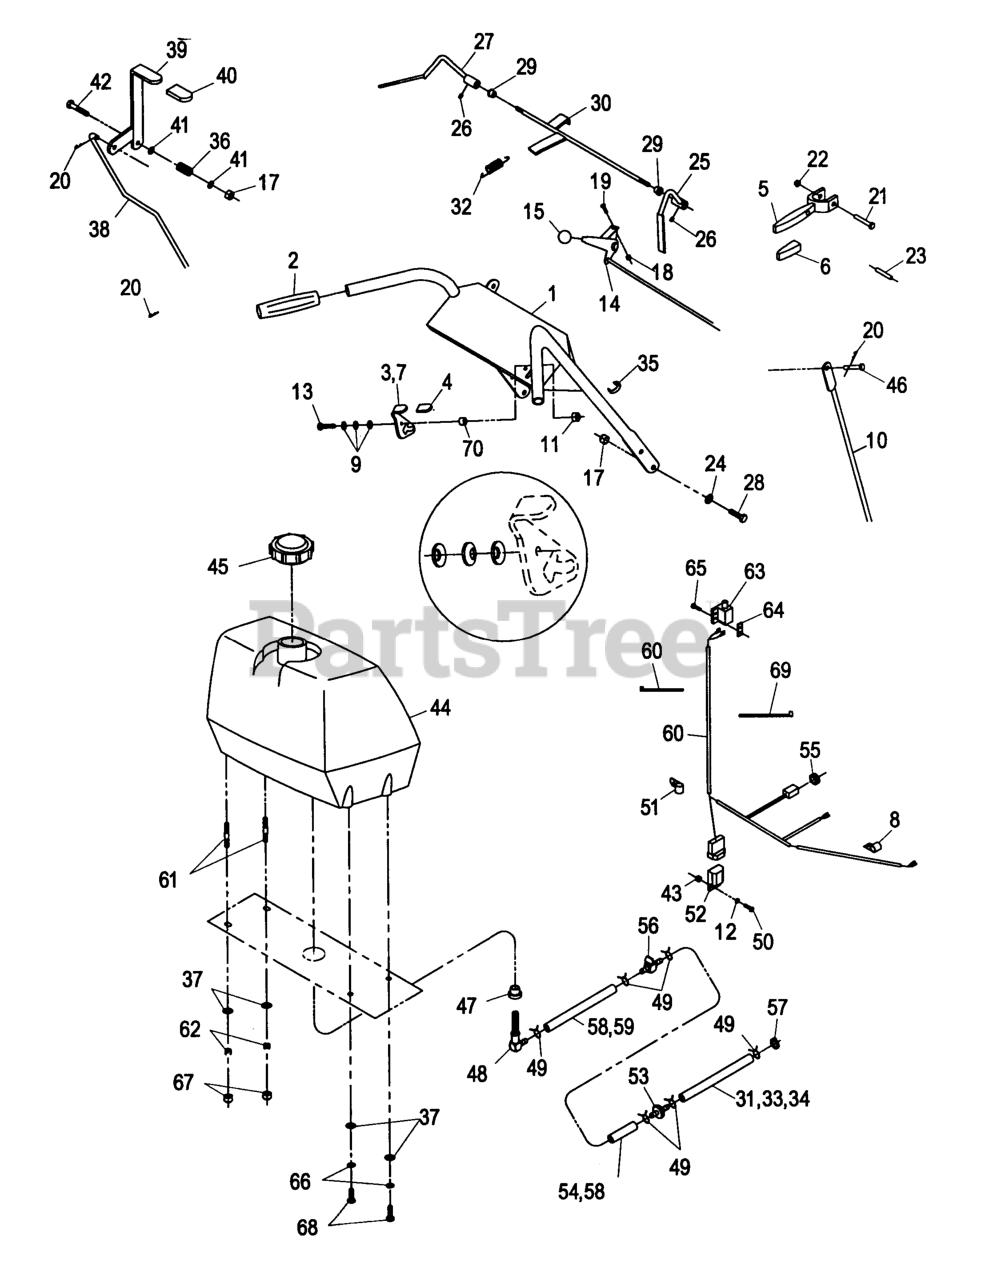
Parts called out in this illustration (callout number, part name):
4	GRIP-LATCH
5	DRIVE LEVER ASM
6	GRIP-LEVER, DRIVE
8	CLIP-LOOM
9	WASHER-SPRING
10	LINKAGE-WHEEL, DRIVE
14	CABLE-CONTROL, THROTTLE
15	KNOB-BALL
16	TIE-CABLE
19	BOLT-CARR
20	PIN-COTTER
21	PIN-LEVER, DRIVE
22	NUT-PUSH
23	PIN-ROLL
25	LEVER-RH
26	SCREW-SET
27	LEVER-LH
29	BUSHING-NYLON
30	WLD,ROD OPC
31	LINE-FUEL
32	SPRING-EXTENSION
33	HOSE-FUEL
34	HOSE-LINE, FUEL
35	CLIP-CABLE
36	SPRING-COMPRESSION
38	LINKAGE-BLADE, UPPER
40	GRIP-LEVER
45	CAP-FUEL
46	PIN-CLEVIS
48	ELBOW-TANK, FUEL
51	CLIP-LOOM
52	MODULE-INTERLOCK
54	HOSE-LINE, FUEL
55	GROMMET
56	VALVE-FUEL
57	CLAMP-HOSE
58	HOSE-FUEL
59	HOSE-FUEL
61	STUD
62	SPRING-TANK, FUEL
63	SWITCH-OPEN, NORMALLY
64	PLATE-TAPPED
66	WASHER-LOCK
69	TIE-PLASTIC
